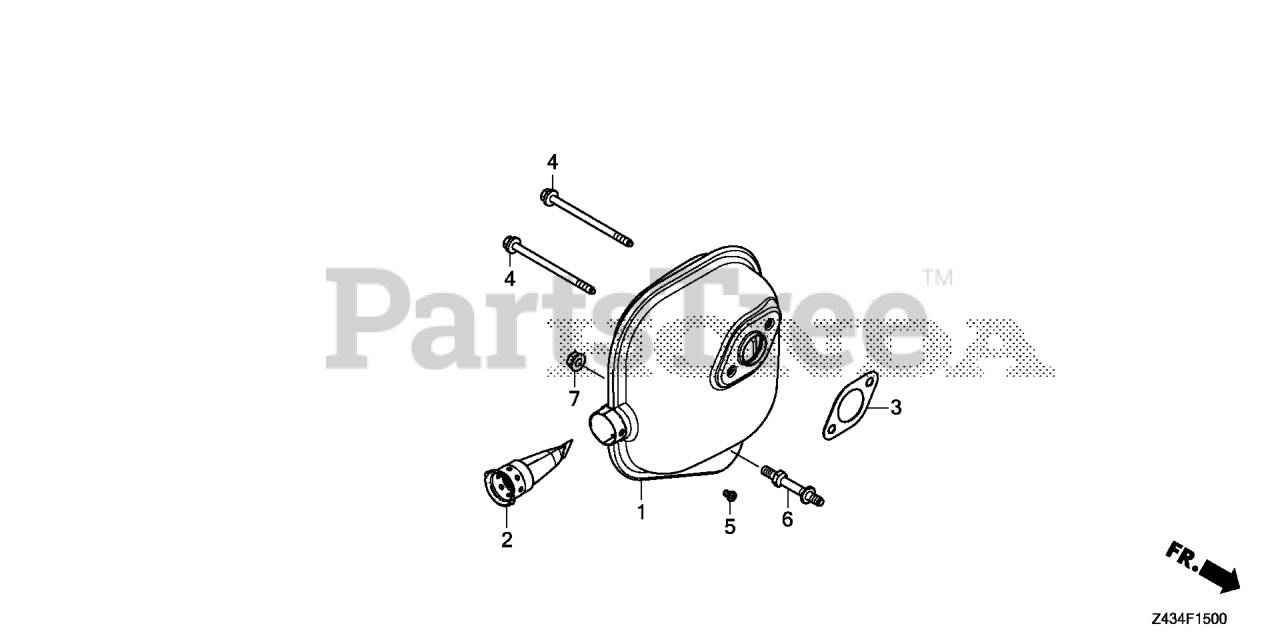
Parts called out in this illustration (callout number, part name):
2	ARRESTER, SPARK
3	GASKET, MUFFLER
4	BOLT, FLANGE (6X79) (CT200)
5	SCREW, TAPPING (4X6) (TO INSTALL OPTIONAL SPARK ARRESTER)
6	BOLT, STUD
7	NUT, FLANGE (6MM)
